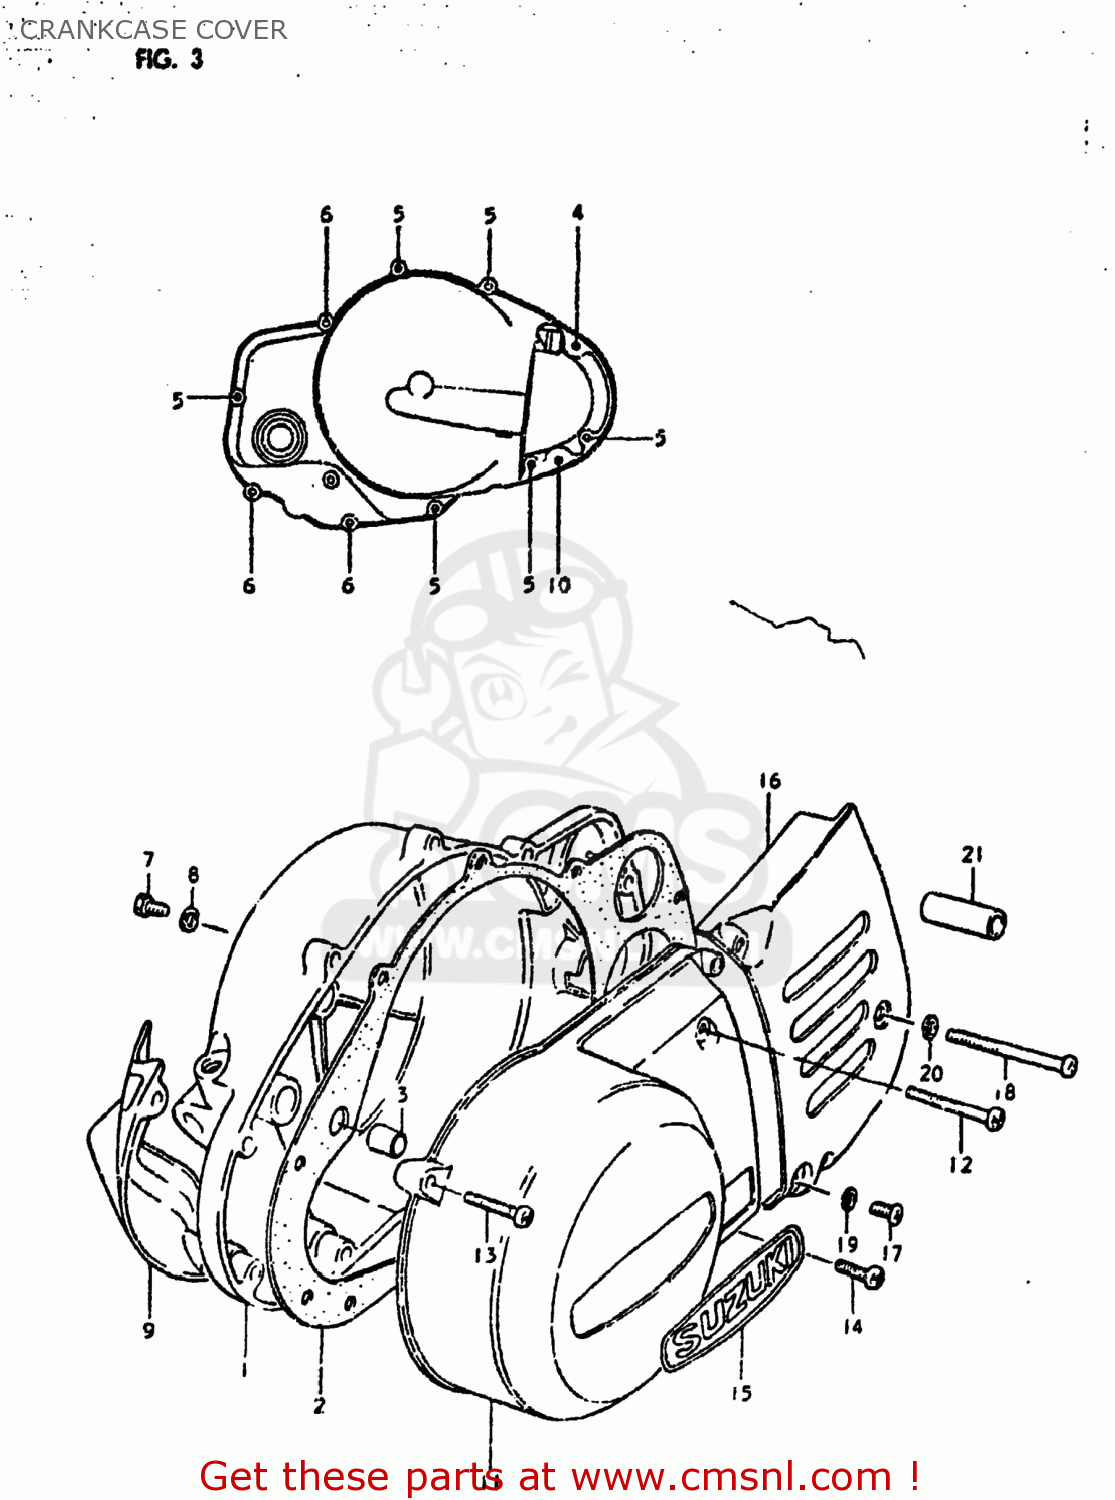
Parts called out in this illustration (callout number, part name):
1	COVER,CLUTCH
2	GASKET,CLUTCH COVER (MCA)
3	PIN
4	SCREW 6X30
5	SCREW
6	SCREW
7	SCREW(6X10)
8	GASKET(6.2X11X1) (NAS)
9	COVER,CLUTCH RELEASE A
10	SCREW
11	COVER,MAGNETO
12	SCREW (6X35)
13	SCREW
14	SCREW
15	EMBLEM,MAGNETO COVER
16	COVER,SPROCKET
17	SCREW
18	SCREW 6X60
19	LOCK WASHER
20	LOCK WASHER
21	CUSHION
